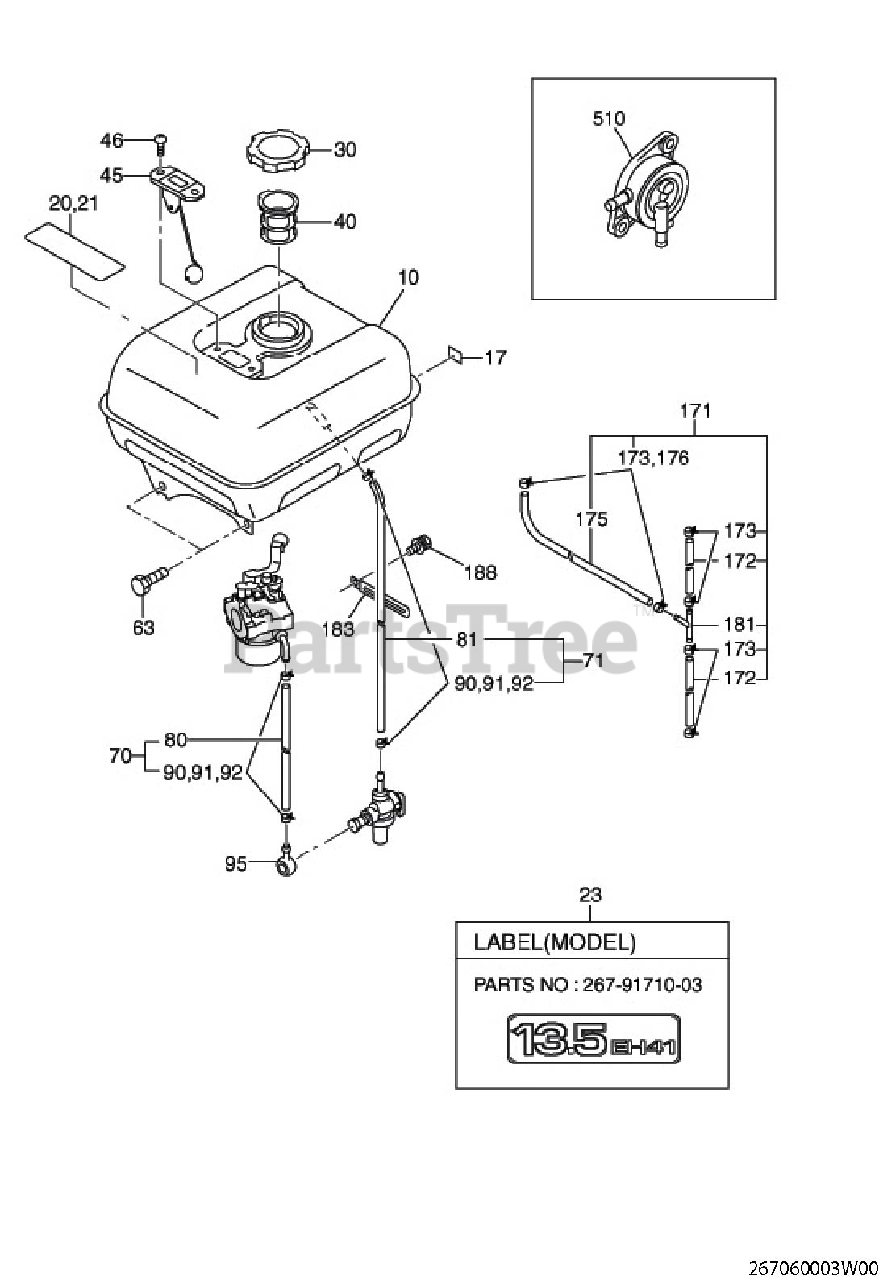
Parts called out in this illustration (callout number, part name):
10	FUEL TANK CP
21	LABEL(WARNING)
30	FUEL TANK CAP CP
40	FUEL FILTER
63	BOLT AND WASHER AY
80	RUBBER PIPE
81	RUBBER PIPE
90	HOSE CLAMP
95	BANJO
